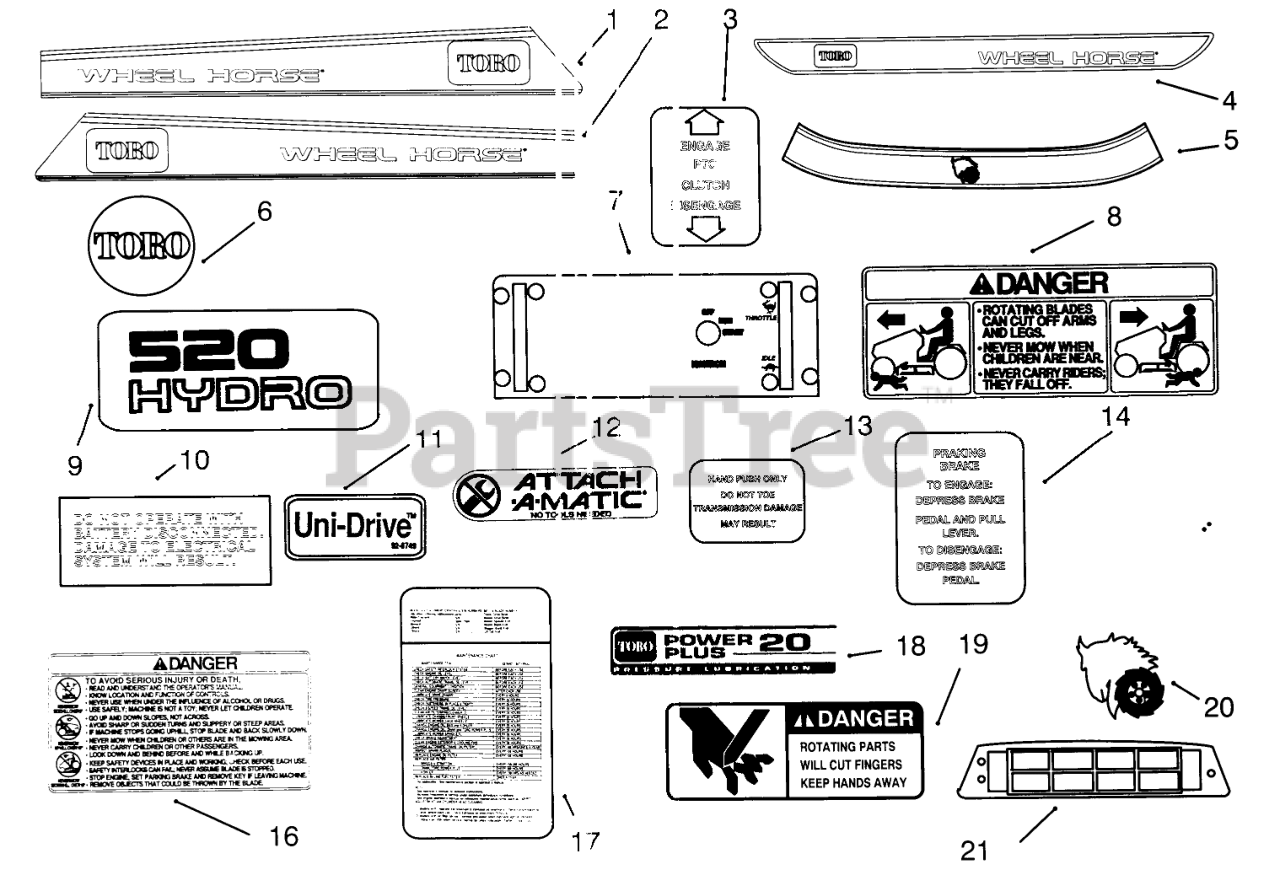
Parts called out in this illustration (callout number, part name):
1	DECAL - RH HOOD TOP
2	DECAL - LH HOOD TOP
3	DECAL PTO CLUTCH
4	DECAL - REAR FENDER
5	DECAL-FRONT HOOD, TOP
6	NAME-PLATE TORO LOGO
7	DECAL-FRONT PANEL
8	DECAL-DANGER
9	Decal-520 Hydro
10	DECAL ELECT SYSTEM
11	Decal-Unidrive
12	DECAL-ATTACH A-MATIC
13	DECAL-DO NOT TOW
14	DECAL-PARKING BRAKE
16	DECAL - DANGER
17	Decal-Maintenance
18	DECAL-PWR PLUS 20 PL
19	DECAL - DANGER
20	PLATE - LOGO WHL HORSE
21	DECAL-IND LIGHTS
